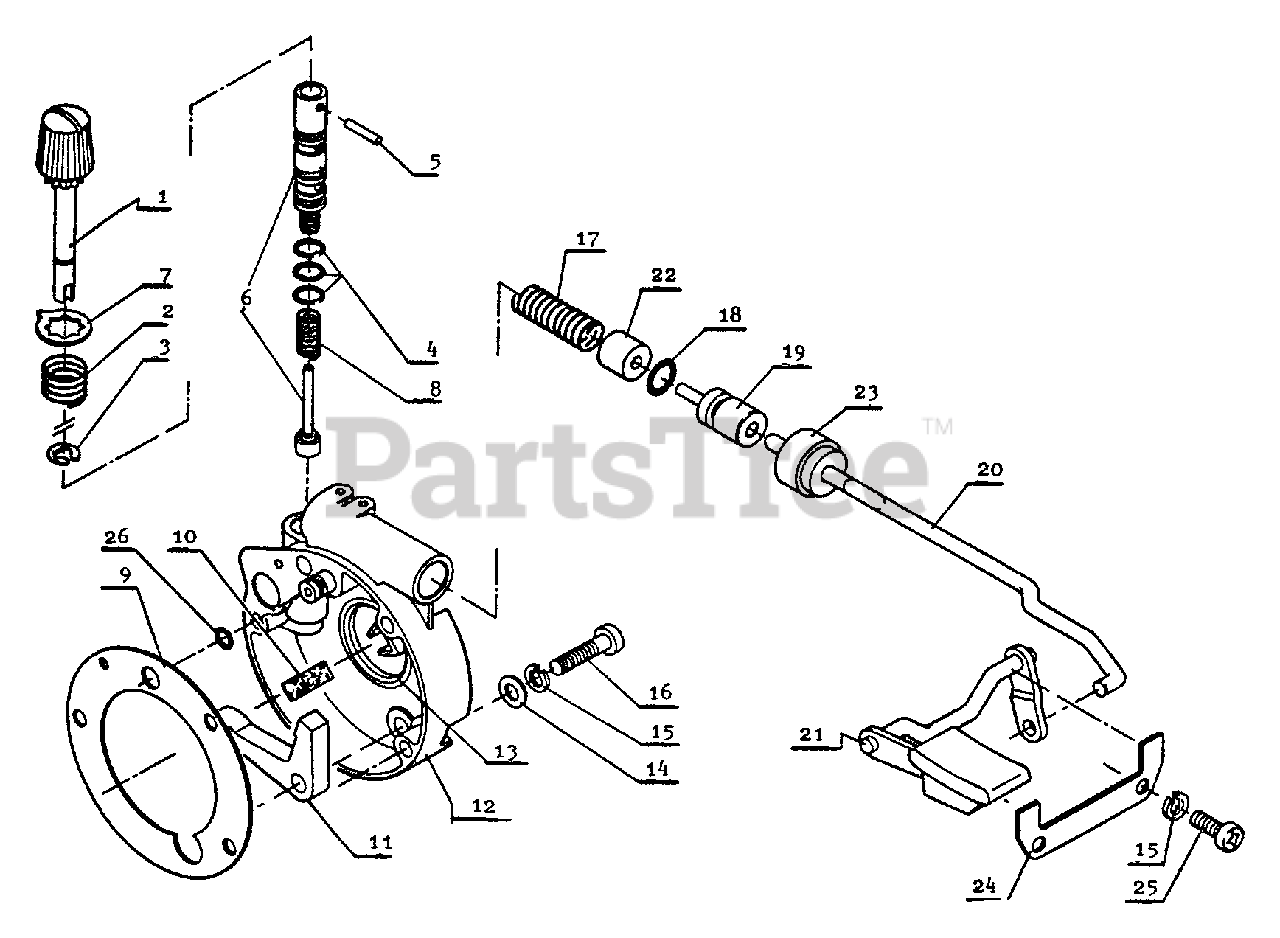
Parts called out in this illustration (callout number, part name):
1	KNOB
2	SPRING
3	RING, RETAINING - 4
4	O-RING - 5
5	PIN - SPRING
6	PUMP KIT
7	DIAL, AUTO-OILER
9	OIL PUMP BODY GASKET
10	PAD
11	ARM, CAM
12	BODY, OIL PUMP
13	SEAL, OIL
14	WASHER - 4
15	LOCKWASHER - 4
16	SCREW - 4X18
17	SPRING, OIL PUMP
18	O-RING - 6
19	PISTON, OIL PUMP
20	Oil pump rod
21	Oil pump lever
22	RETAINER, SPRING
23	PISTON COVER
24	Oil pump lever retainer
25	SCREW - 4X10
26	O-RING - 4
